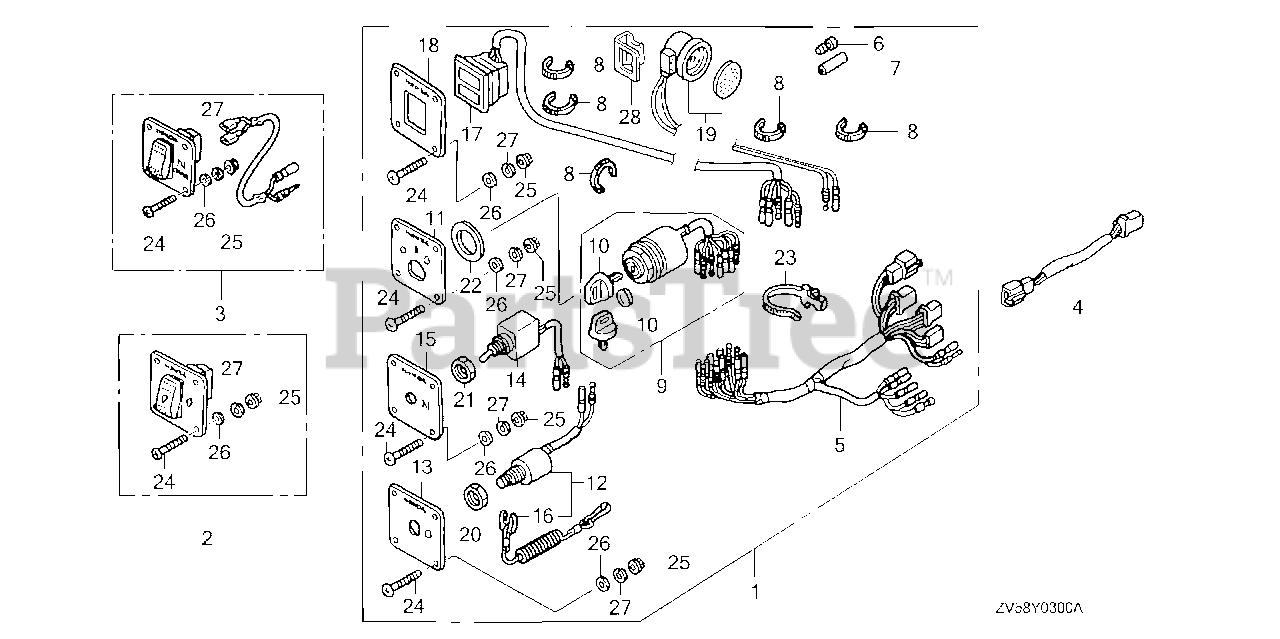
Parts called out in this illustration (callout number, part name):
1	PANEL KIT, CONTROL (B)
5	HARNESS ASSY., SWITCH PANEL
6	PLUG, CONNECTOR (INNER)
7	PLUG, CONNECTOR (OUTER)
8	TIE, CABLE (2.4X92) (NATURAL)
9	SWITCH ASSY., COMBINATION
10	KEY ASSY., COMBINATION SWITCH (35100-ZV5-003 ONLY)
11	PANEL, SWITCH
12	SWITCH ASSY., EMERGENCY STOP
13	PANEL, EMERGENCY STOP SWITCH
14	SWITCH ASSY., SOLENOID
15	PANEL, SOLENOID
16	WIRE, EMERGENCY
17	LAMP ASSY., INDICATOR (2-LED)
18	PANEL, INDICATOR
19	BUZZER, WARNING
20	NUT, HEX. (16MM)
21	NUT, HEX. (12MM)
22	WASHER, PLAIN
23	BAND, WIRE HARNESS (150MM) (NATURAL)
24	SCREW, PAN (5X40)
25	NUT, FLANGE (5MM)
26	WASHER, PLAIN (5MM)
27	WASHER, SPRING (5MM)
28	BRACKET, BUZZER
